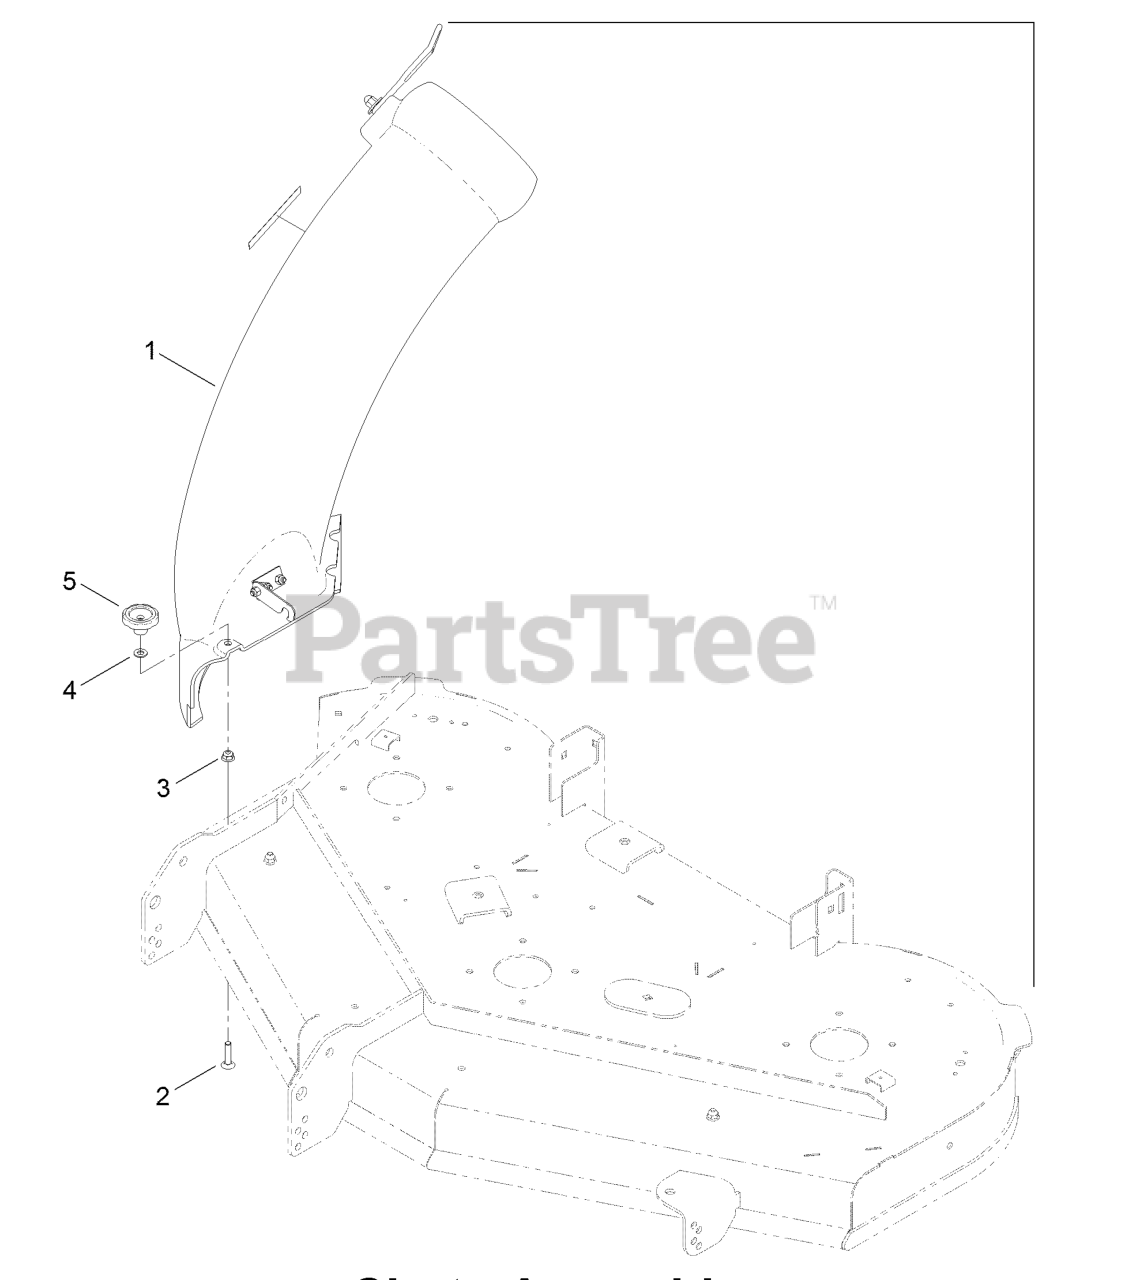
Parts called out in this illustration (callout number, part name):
1	50 INCH CHUTE ASM
2	SCREW-CARR
3	NUT-HF, NI
4	WASHER-PLAIN
